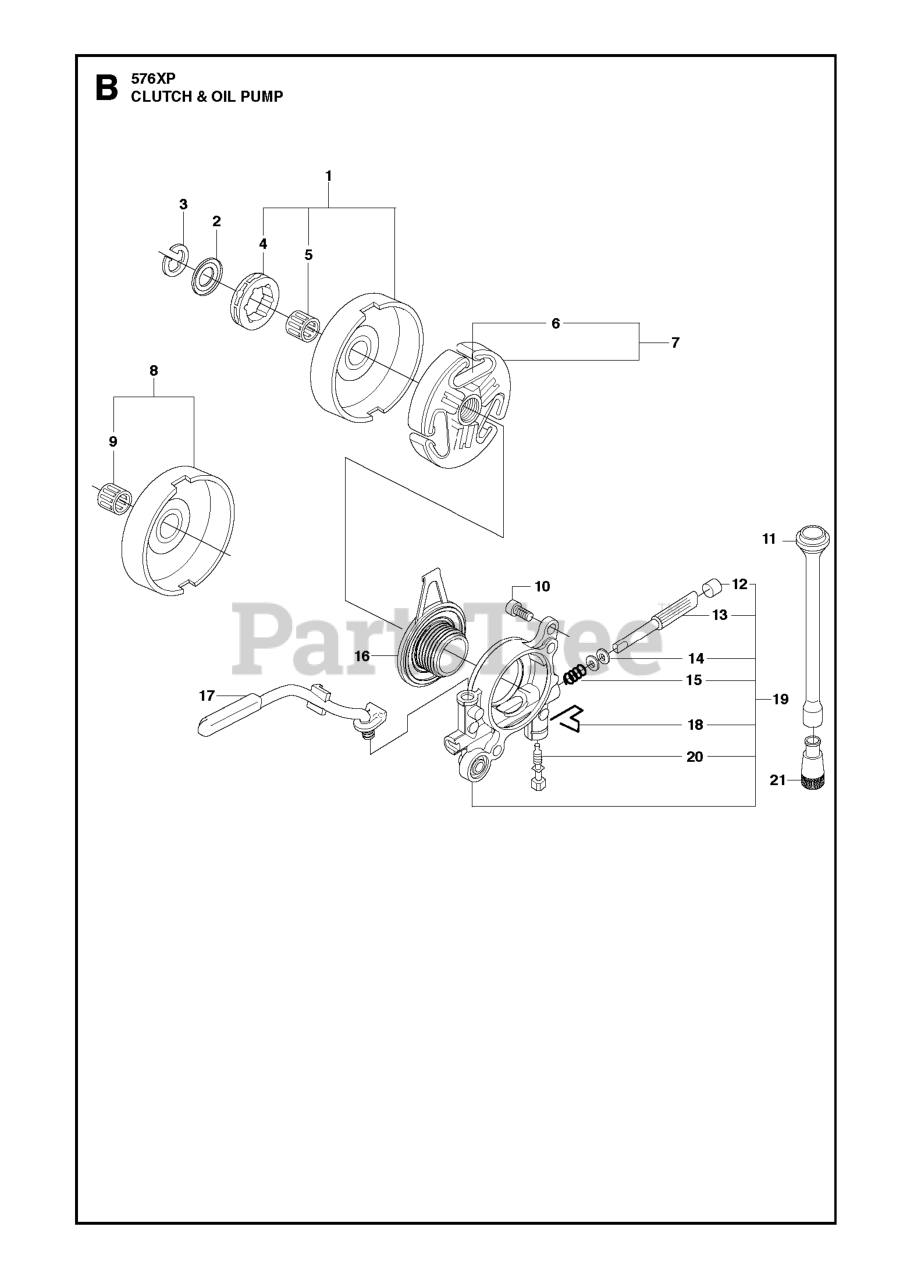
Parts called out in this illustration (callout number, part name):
1	CLUTCH DRUM ASSY STD 7 SPLINES
1	CLUTCH DRUM ASSY
3	RETAINING RING
4	22273 Sprocket 3/8"x8T
4	68210 RIMSPROCKET
5	CLUTCH DRUM BEARING
7	CLUTCH
8	CLUTCH DRUM
9	CLUTCH DRUM BEARING
13	PUMP PISTON
14	WASHER 6.1X9
16	PINION
18	SPRING CLIP
19	OIL PUMP
21	OIL SCREEN
